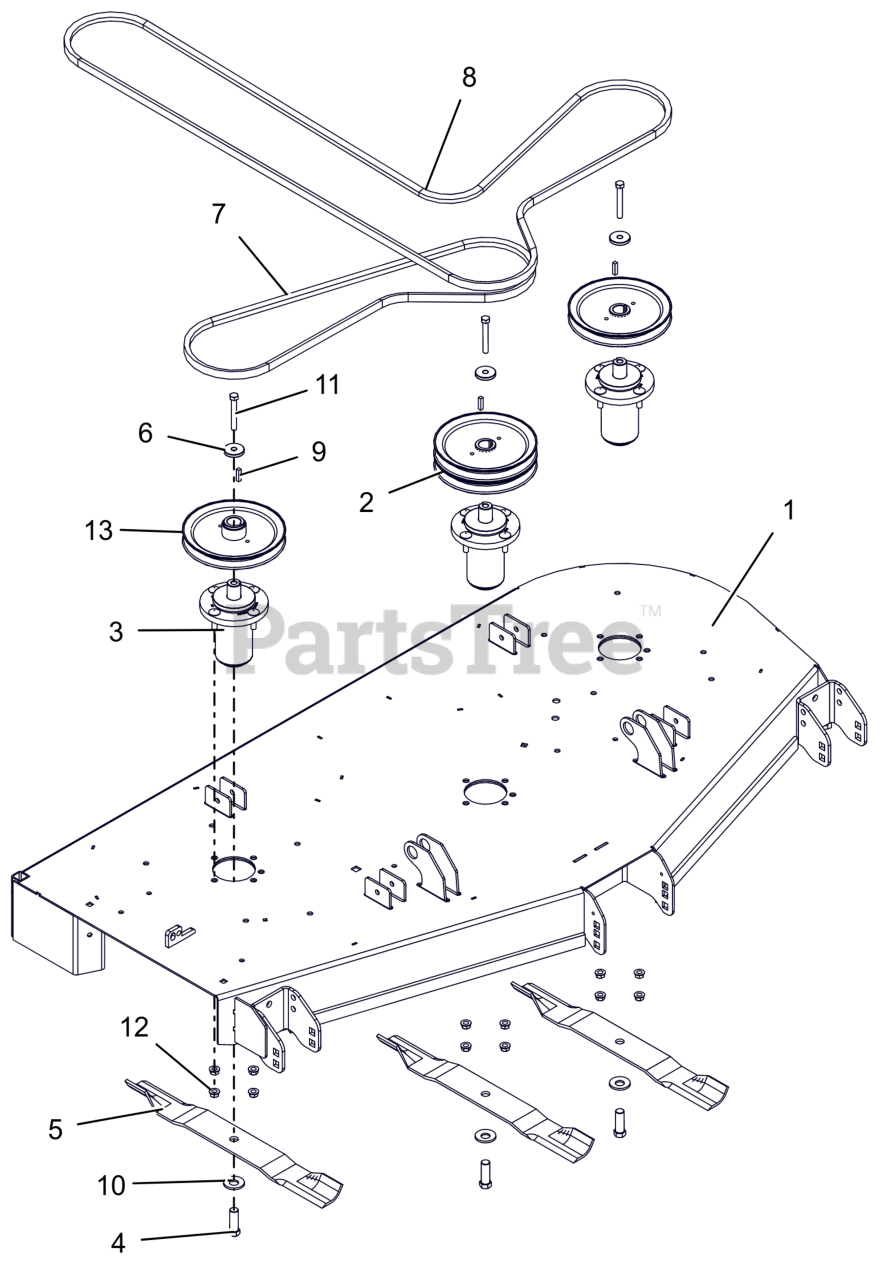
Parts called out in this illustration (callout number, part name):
1	KIT,DECK-60" W/DECALS-GRAVELY
2	PULLEY, DOUBLE 1"X7.50"&7.50" (BLACK)
3	ASM, MAINT FREE ALUM SPINDLE
4	BLT, HEX .62-18X1.75 G8 ZCC
5	BLADE, 20.5"
6	RETAINER, SHEAVE
7	V-BELT, B-COGGED
8	V-BELT, HB SECTION
9	KEY, SQ .25X.25X1.00 RC 40-50
10	WSHR-BLVL .669X1.535X.138
11	BLT, HEX .38-16X2.75 G8 ZCC
12	NUT-LK-CTR-FLG .375-16 GF ZCC
13	PULLEY, V-7.50 OD X 1"ID
